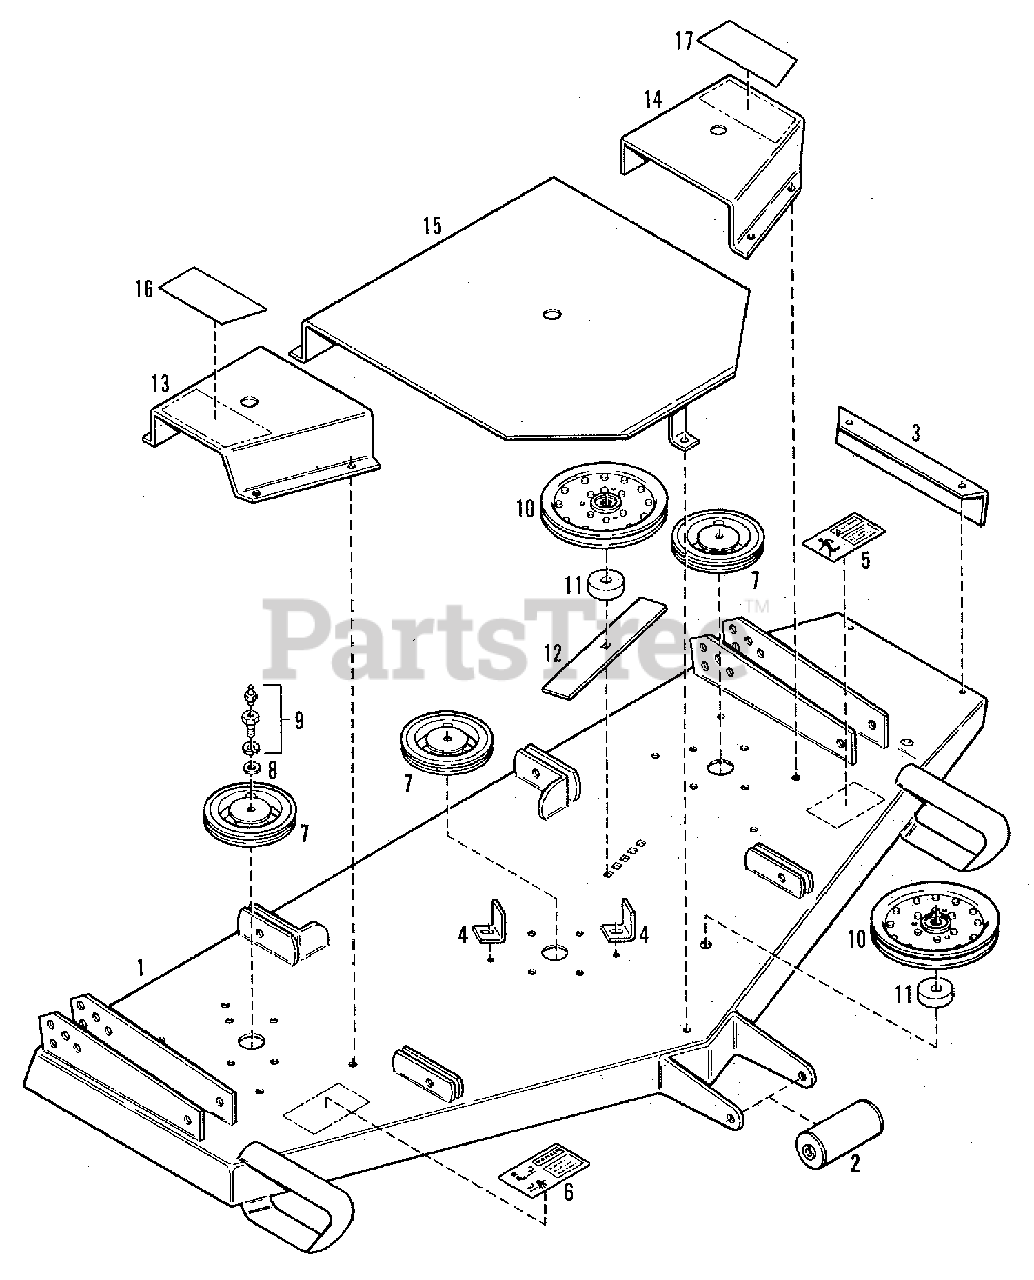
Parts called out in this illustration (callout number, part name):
1	DECK, Mower, 54"
2	ROLLER ASSEMBLY, Anti-Scalp
2	BOLT, Carriage, 1/2NC x 7-1/2
2	NUT, Lock, w/Nylok
3	DEFLECTOR, Mulch Cap
3	BOLT, Carriage, 3/8NC x 1
3	LOCKWASHER, 3/8
4	GUIDE, Belt Retainer
4	BOLT, Carriage, 3/8NC x 1
4	LOCKWAHER, 3/8
5	DECAL, Warning-Discharge
6	DECAL, Danger-Blade
7	PULLEY, Drive
8	WASHER, Flat, Spindle
9	SCREW, Spindle, 1/2NC x 3/4
9	LOCKWASHER, 1/2
9	FITTING, Grease, 1/4NF Straight
10	IDLER, Back Side
10	BOLT, Carriage, 5/8NC x 2-1/2
10	NUT, Lock, 5/8NC
11	SPACER, Bottom
12	LEVER, Cover Strap
13	SHIELD, Belt, R.H.
13	BOLT, Carriage, 5/16NC x 3/4
13	LOCKWASHER, 5/16
13	NUT, 5/16NC
14	SHIELD, Belt, L.H.
14	BOLT, Carriage, 5/16NC x 3/4
14	LOCKWASHER, 5/16
14	NUT, 5/16NC
15	SHIELD ASSEMBLY, Center
15	BOLT, Carriage, 5/16NC x 3/4
15	LOCKWASHER, 5/16
15	NUT, 5/16NC
16	TAPE, Safety Walk, R.H.
17	TAPE Safety Walk, L.H.
18	SCREEN, Grille-Cut-Out
